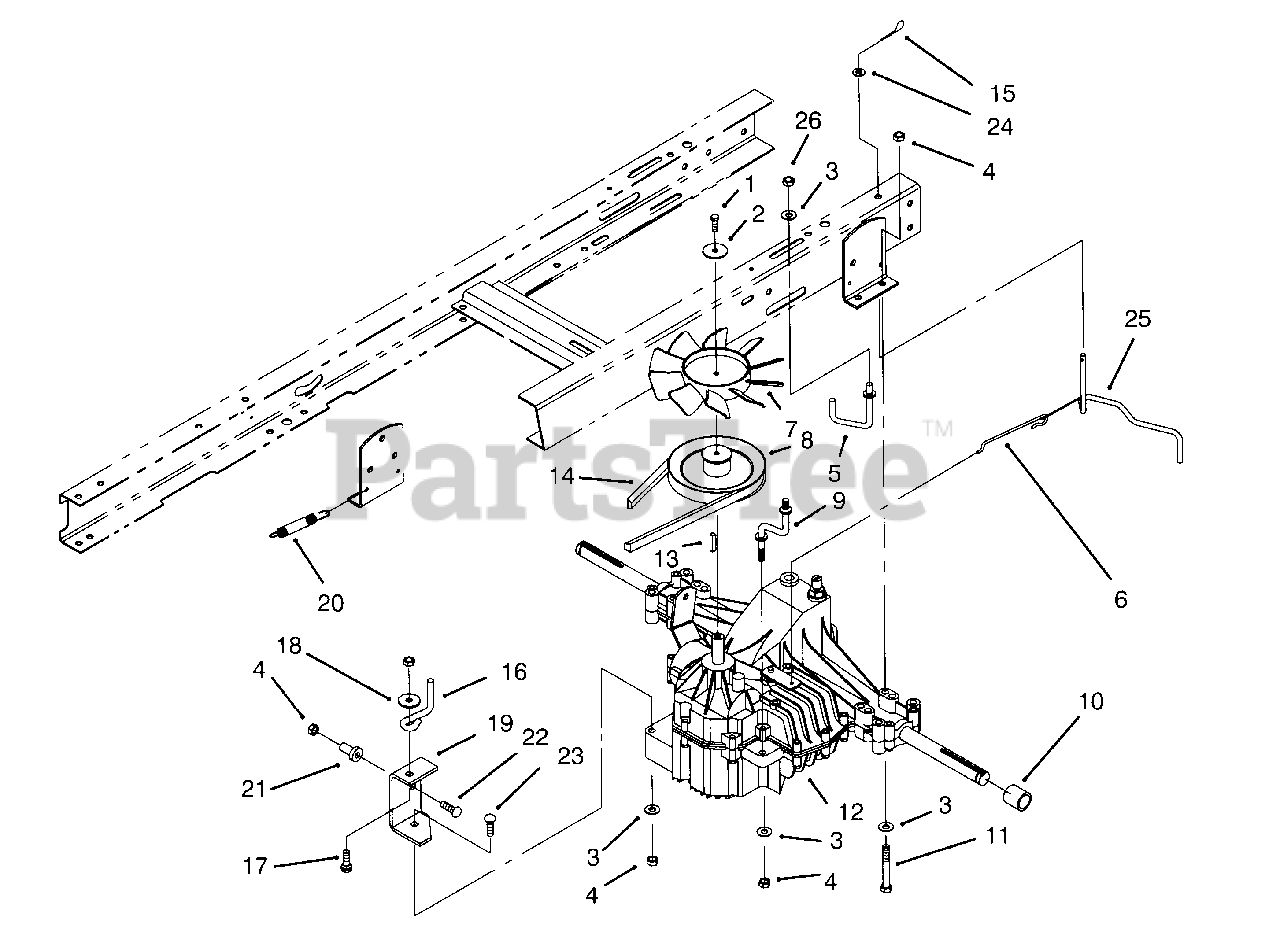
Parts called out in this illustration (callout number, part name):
1	Screw-Hex Hd. Cap
2	Washer-Flat
3	Washer-Flat
4	Nut-Lock
5	Guide-Trans. Belt L.H.
6	Wire-Bypass
7	Fan-Hydro
8	Pulley-Transaxle
9	Strap-Torque
10	Spacer-Wheel
11	Screw-Hex Hd. Cap
12	Transaxle
13	Key-Square
14	V-Belt-Transaxle
15	Pin-Hair Cotter
16	Belt Guide-Trans.
17	Bolt-Carriage
18	Washer-Fender
19	Bracket-Speed Control
20	Spring-Brake Return
21	Bushing-Flanged
22	Bolt-Carriage
23	Bolt-Carriage
24	Washer-Flat
25	Lever-Bypass
26	Nut-Keps
